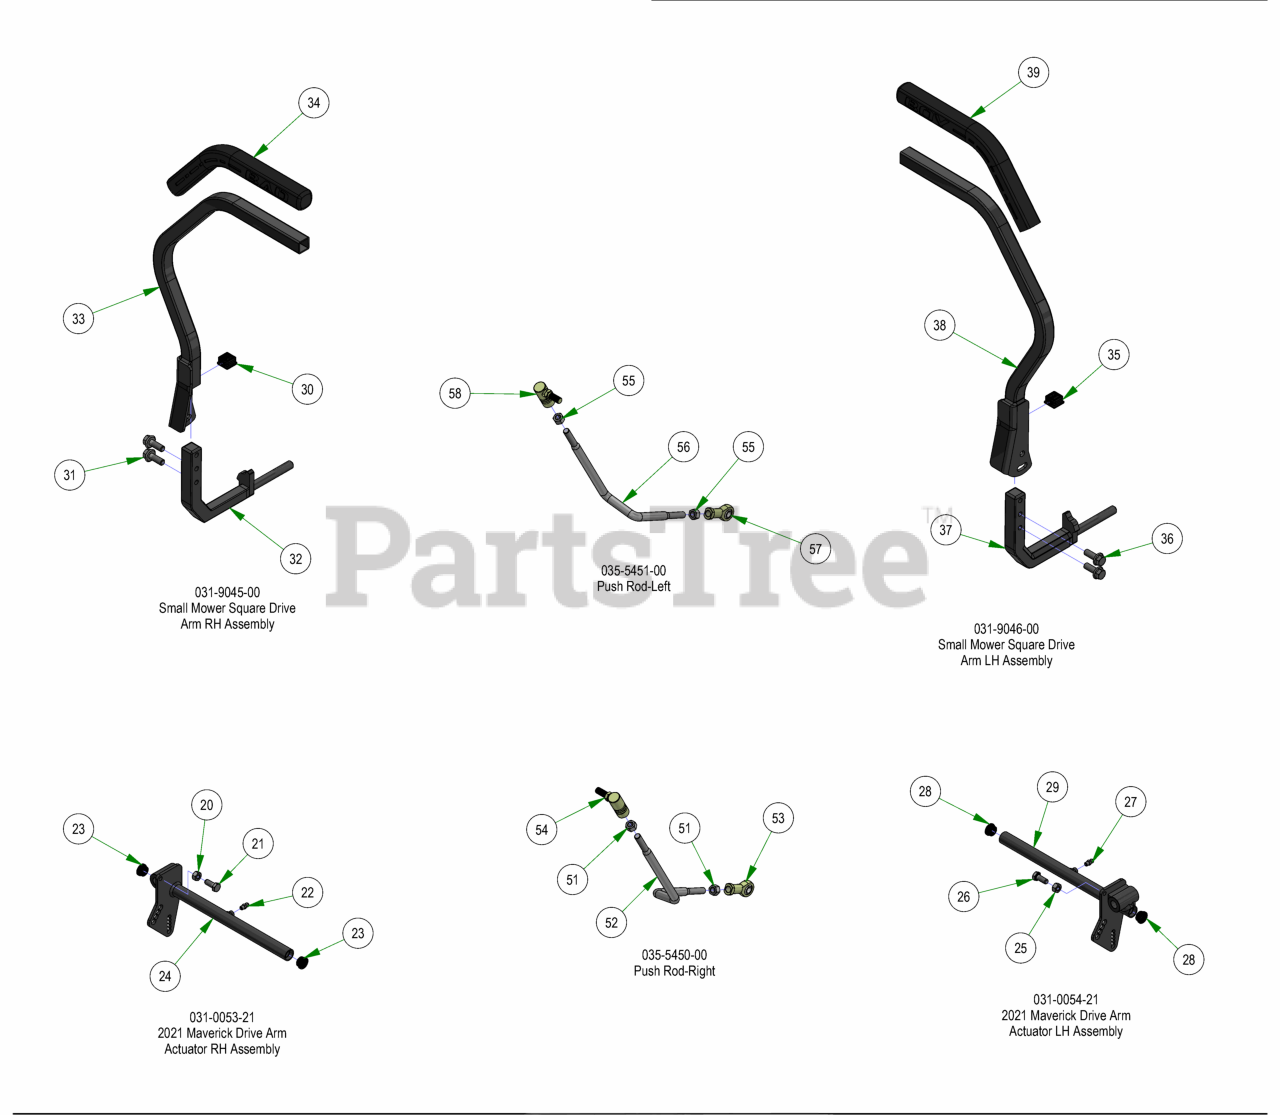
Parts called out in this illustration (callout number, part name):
20	5/16-18 HEX NUT ZINC
21	5/16-18 X 3/4 HEX CAP SCREW (GR.5) ZINC
22	1/4 DRIVE-TYPE STRAIGHT GREASE FITTING ZINC YELLOW)
23	2019 Drive Arm Bushing
24	2021 Drive Actuator RH Weldment
25	5/16-18 HEX NUT ZINC
26	5/16-18 X 3/4 HEX CAP SCREW (GR.5) ZINC
27	1/4 DRIVE-TYPE STRAIGHT GREASE FITTING ZINC YELLOW)
28	2019 Drive Arm Bushing
29	2021 Drive Actuator LH Weldment
30	9565K16_Polyethylene Square Plug
31	92323A554_Grade 5 Steel Serrated-Flange Hex Head Screw
32	Small Mower Square Drive Arm Lower RH Weldment
33	Small Mower Square Drive Arm RH Weldment
34	Grip for 031-9045-00 / 031-9046-00
35	9565K16_Polyethylene Square Plug
36	92323A554_Grade 5 Steel Serrated-Flange Hex Head Screw
37	Small Mower Square Drive Arm Lower LH Weldment
38	Small Mower Square Drive Arm LH Weldment
39	Grip for 031-9045-00 / 031-9046-00
51	3/8" Fine Threaded Jam Nut
52	Push Rod - Right (Rod Only)
53	Spherical Rod End - Outlaw
54	Quick Release Ball Joint
55	3/8" Fine Threaded Jam Nut
56	Push Rod LH (Rod Only)
57	Spherical Rod End - Outlaw
58	Quick Release Ball Joint
90	2022 Maverick RH Front Suspension Arm Assy (42'')
91	2022 Maverick LH Front Suspension Arm Assy (42'')
